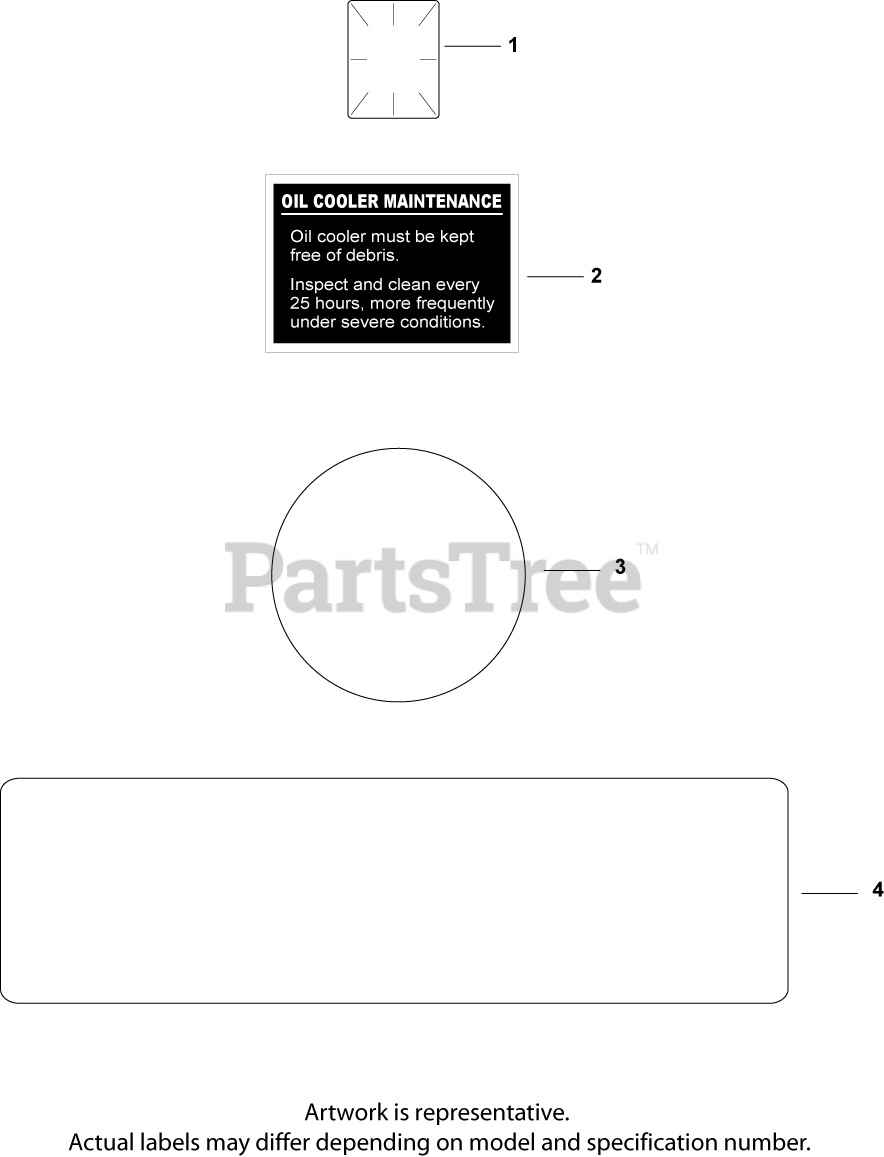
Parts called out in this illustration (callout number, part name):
1	DECAL, CLEAR LAMINATE USE 25 113 70-S
2	DECAL, OIL COOLER - (#DSC)
3	DECAL, GRASS SCREEN USE 24 113 499-S
4	DECAL, 25 HP - DISCONTINUED
